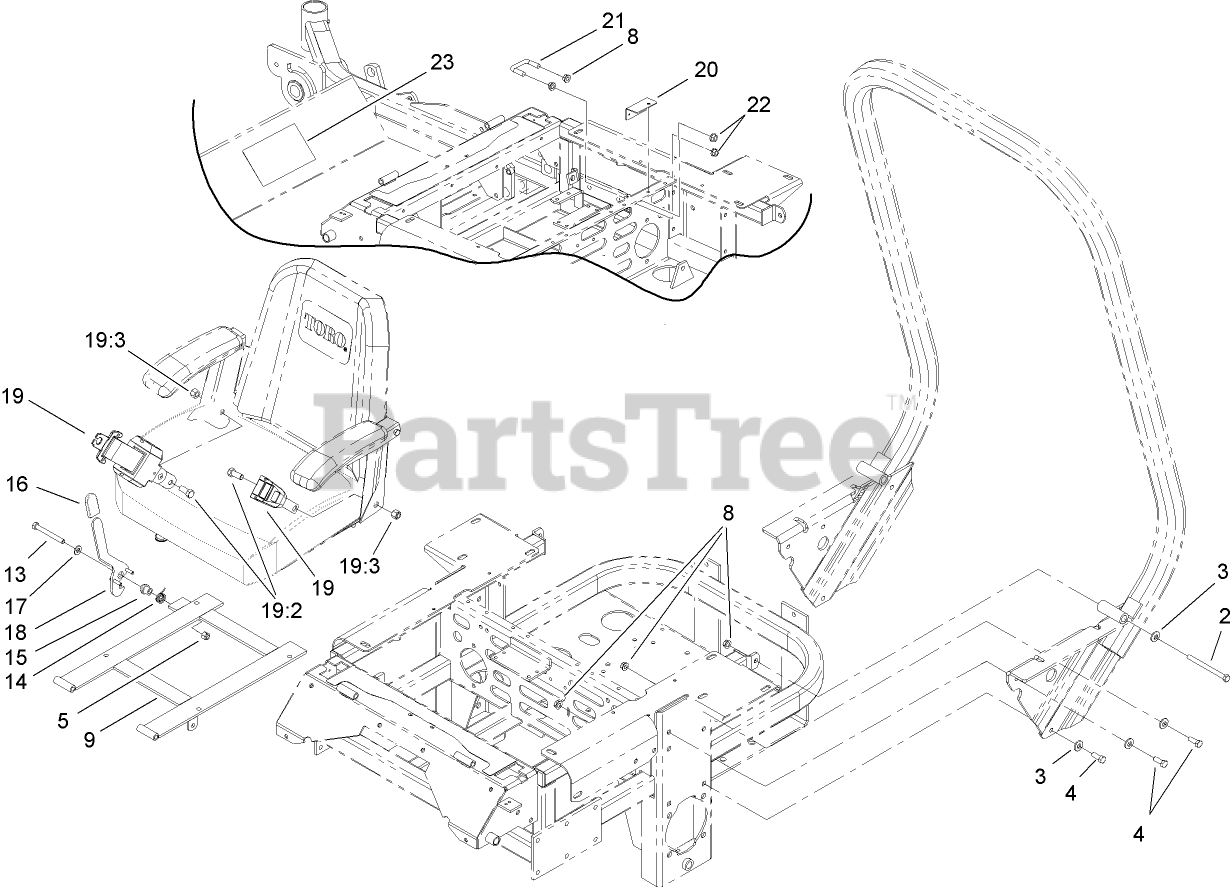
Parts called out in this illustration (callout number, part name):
2	SCREW-HH
3	WASHER-BELLEVILLE
4	SCREW-HH
5	NUT-LOCK, NI
8	NUT-HHF, WHIZ
9	SEAT SUPPORT FRAME ASM
13	SCREW-HH
14	SPRING-TORSION
15	BUSHING-LATCH, SEAT
16	GRIP-LEVER
17	WASHER-FLAT
18	LATCH ASM
19	RETRACTABLE SEATBELT KIT
19:2	SCREW-HH
19:3	NUT-LOCK
20	TEMPLATE-DRILL, SEAT CATCH
21	U-BOLT
22	NUT-HF
23	DECAL-WARNING, SLOPE ROPS
